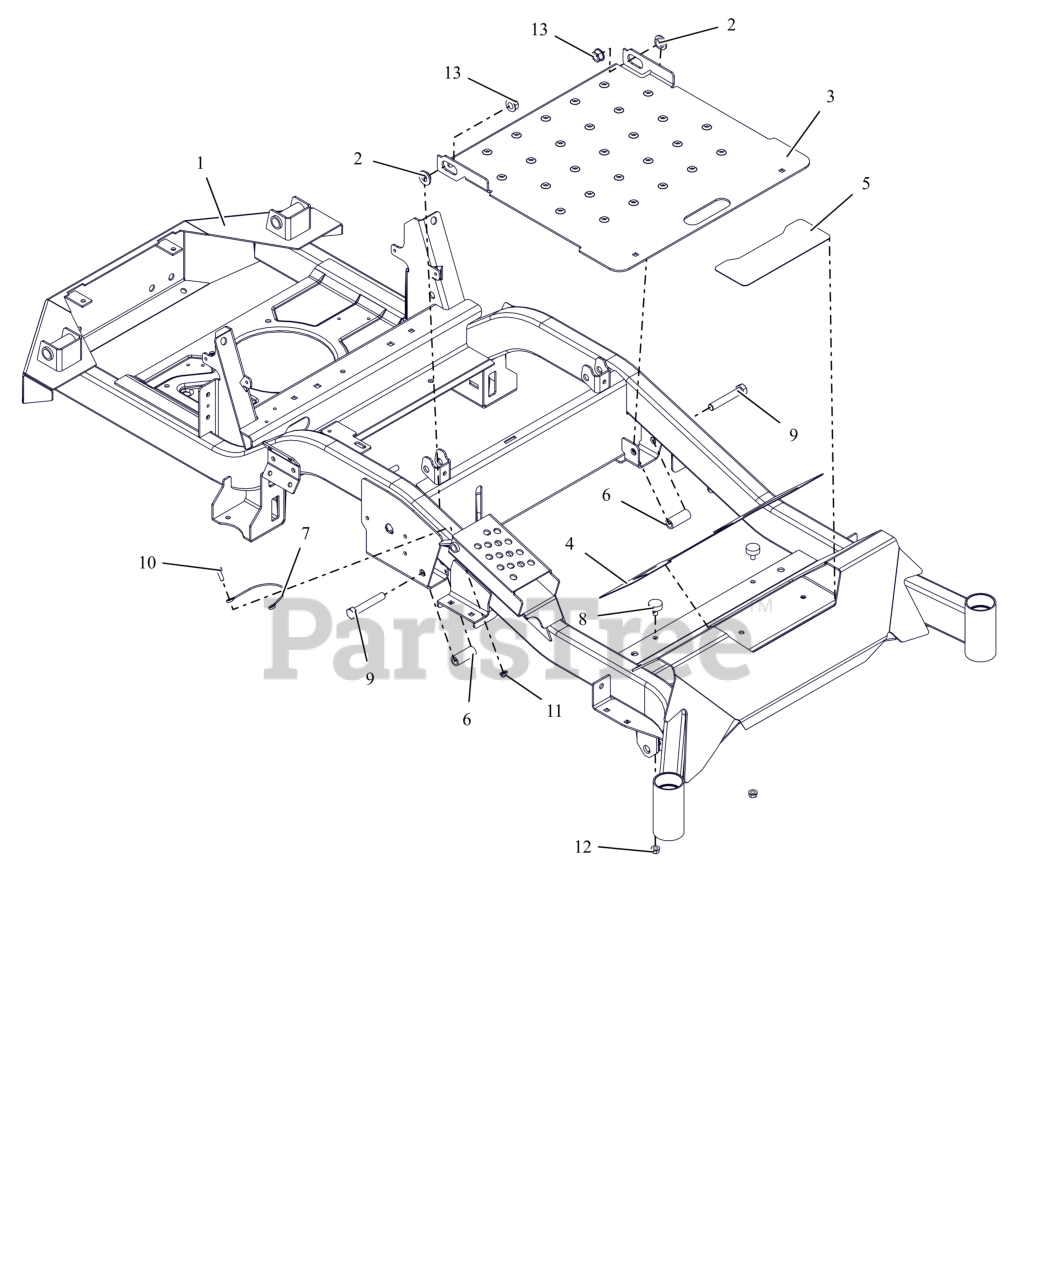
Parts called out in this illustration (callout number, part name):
1	APEX,44-52 FRAME W/SAFETY DECA
2	BSHG-FLG .515X.750X.395X1.120
3	PANEL, ACCESS
4	GRIP, FRONT
5	GRIP, STEP
6	SPACER, .515X.75X1.83
7	CABLE, 12.0 LANYARD, NYLON
8	BUMPER, RUBBER
9	BLT, HEX .50-13X3.00 G5 ZCC
10	BLT, HEX .25-20X.75 G5 ZCC
11	NUT,NYL-FLG .25-20 GF ZCC
12	NUT,SPNLK-FLG .31-18 G5 ZCC
13	NUT-LK-TOP-FLG .500-13 GF ZCC
